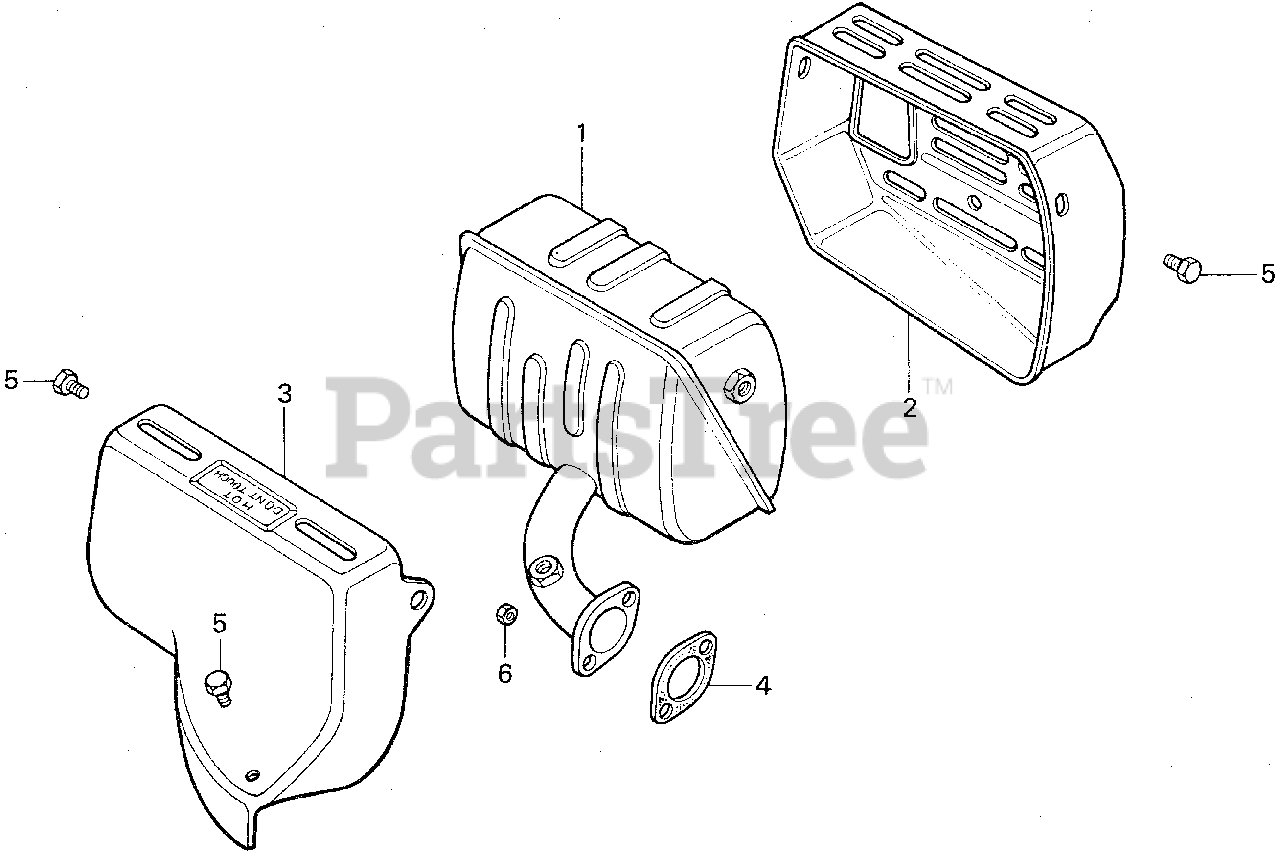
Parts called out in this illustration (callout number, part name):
1	MUFFLER (NOT AVAILABLE)
2	PROTECTOR, MUFFLER
3	SEPARATOR, MUFFLER (NOT AVAILABLE)
4	GASKET, MUFFLER
5	BOLT, HEX. (6X6)
6	NUT, HEX. (6MM)
